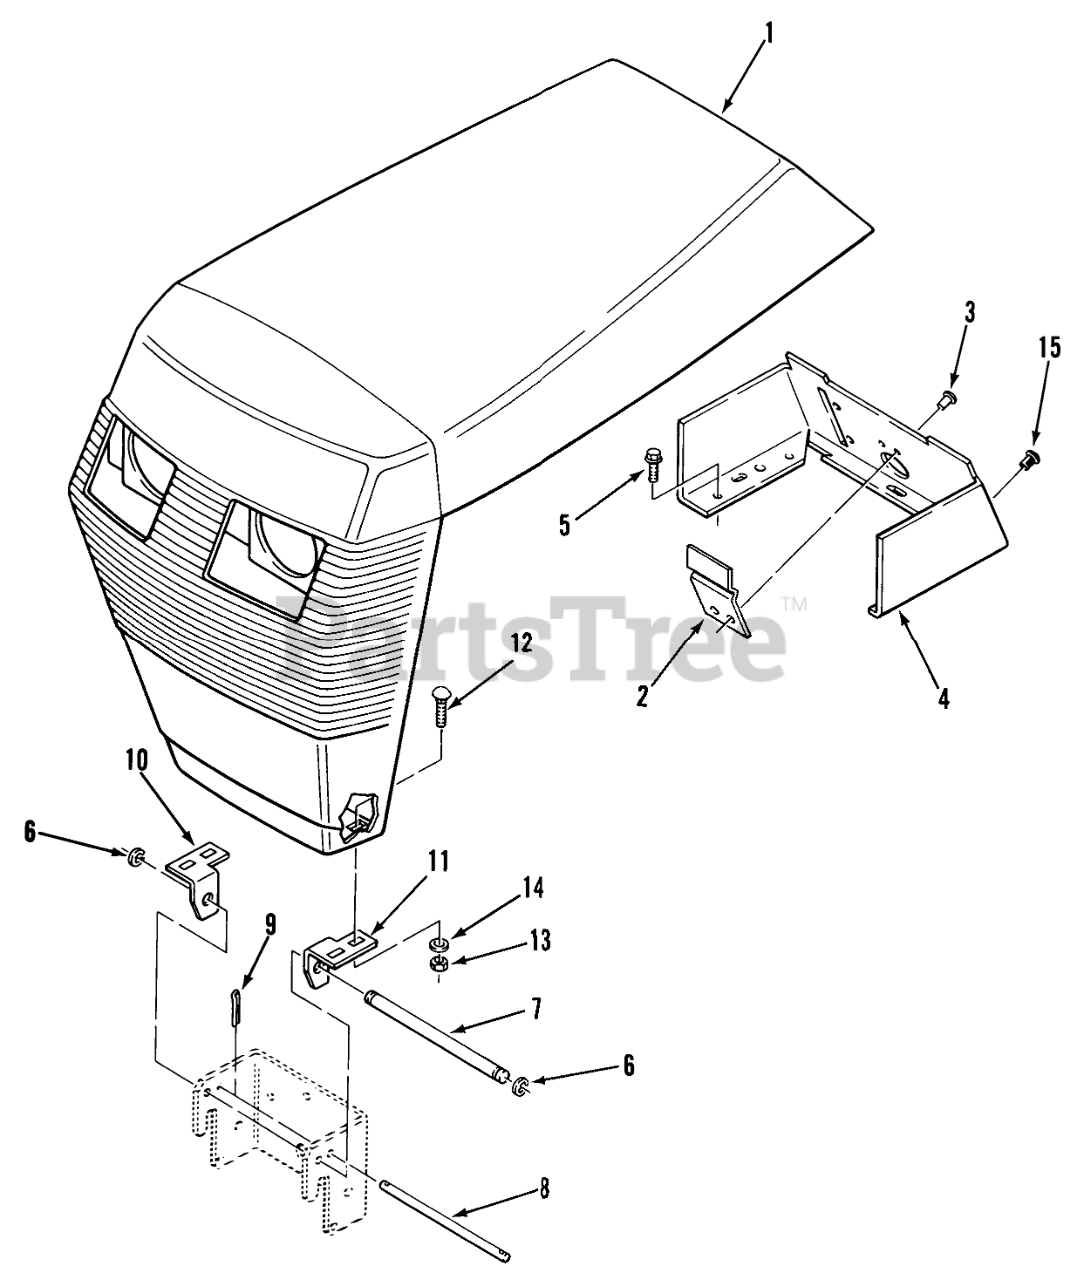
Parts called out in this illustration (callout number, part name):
2	Hood Latch
3	RIVET
4	Console
5	SCREW
6	RING-RETAINING
7	GRILL PIVOT ROD
8	ROD-HOOD STOP
9	Cotter Pin
10	BRKT-GRILL PIVOT R
11	BRKT-GRILL PIVOT R (NS)
12	Bolt 1/4-20 X 5/8
14	Nut
15	NYLON PLUG
